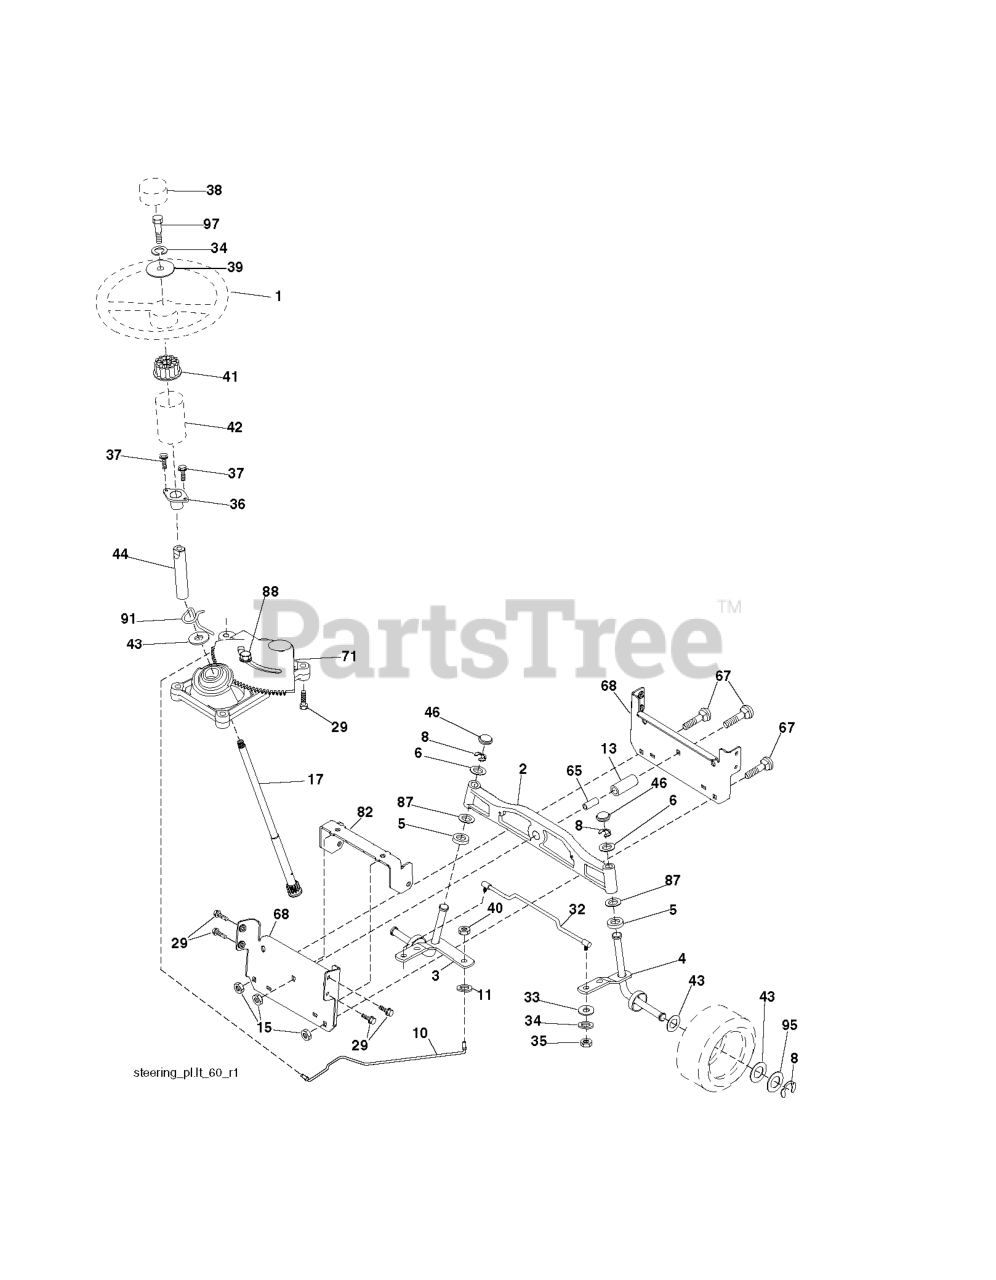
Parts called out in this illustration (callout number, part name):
1	STEERING WHEEL
2	AXLE ASSY FRONT
3	SPINDLE.ASM.LH.15"TIRES
4	SPINDLE.ASM.RH.15"TIRES
5	THRUST WASHER
10	DRAGLINK.15".TIRES.2001
11	WASHER, LOCK 3/8
13	TUBE, PIVOT AXLE
15	NUT
17	SHAFT STEERING SPLINE
29	SCREW, 3/8-16X3/4
32	TIE ROD
33	WASHER M
34	WASHER.LOCK.HVY.HLCL.SPR.5/16
35	NUT, CROWNLOCK
36	BUSHING, STEERING
37	SCREW.TT.#10-32X.5.3/8.FLANGE
38	INSERT.CAP.STRG.WH.GRAY
39	WASHER.11/32
40	NUT CROWNLOCK 3/8-24
41	ADAPTER, WHEEL STNG..
42	BOOT, STEERING
44	SHAFT.EXTEN.STRG.SPLINE
46	CAP.SPINDLE.BLACK
65	SPACER BRACE AXLE
67	BOLT CARRIAGE
68	BRACE.AXLE.15"TIRES
71	STEERING ASM
82	BRACKET.SUSP.CHASSIS.FRONT.15
87	WASHER, FLAT .781 X 1 1/2"
88	BOLT, SHOULDER 7/16-20
91	CLIP.STEERING
95	WASHER.HARDENED
